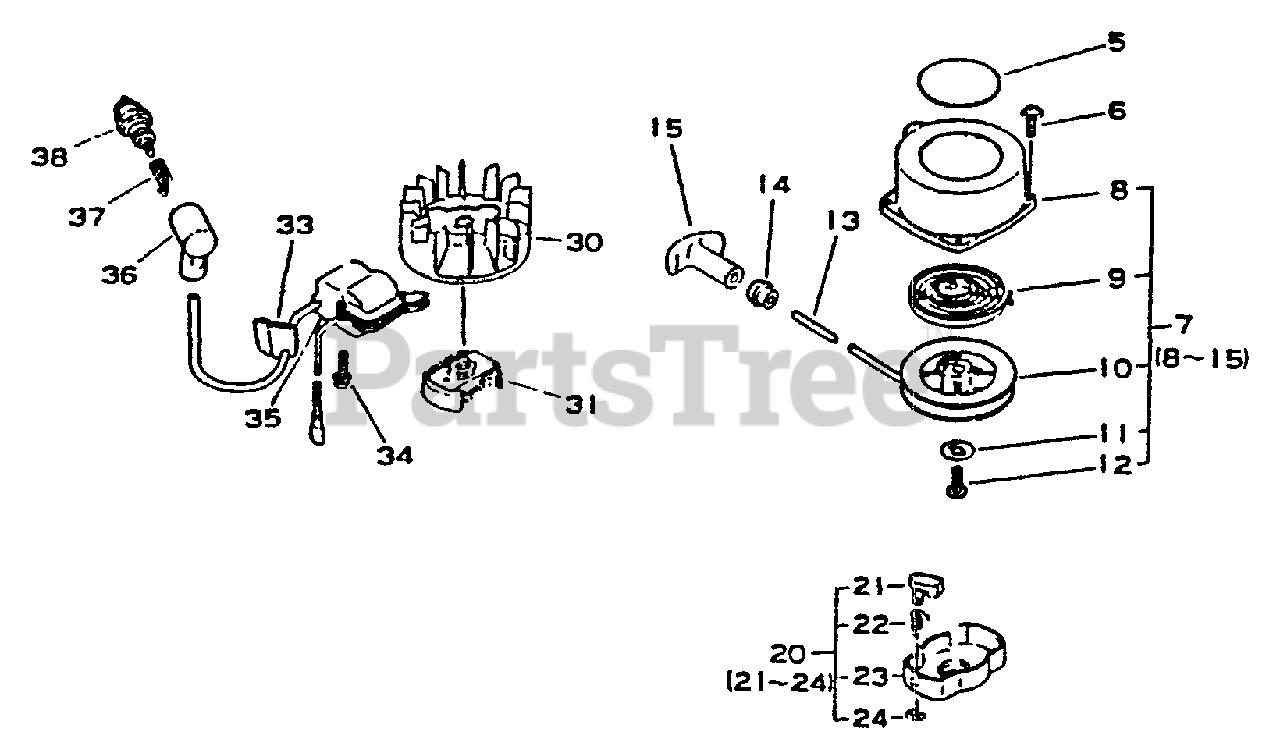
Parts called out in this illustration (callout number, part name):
5	LABEL - ECHO
6	SCREW 4×16
7	STARTER ASSY
8	CASE, RECOIL STARTER
9	SPRING, RECOIL
10	REEL, ROPE
11	WASHER
13	ROPE, STARTER
14	GUIDE, ROPE
15	GRIP, STARTER
20	STARTER PAWL ASSY
21	PAWL, STARTER
22	SPRING, RETURN
23	CATCHER, PAWL
24	E-RING 4
30	FLYWHEEL
31	CLUTCH ASSY
34	SCREW 4×22
35	COIL, IGNITION
36	CAP, SPARK PLUG
37	TERMINAL, SPARK PLUG
38	SPARK PLUG - CJ8
